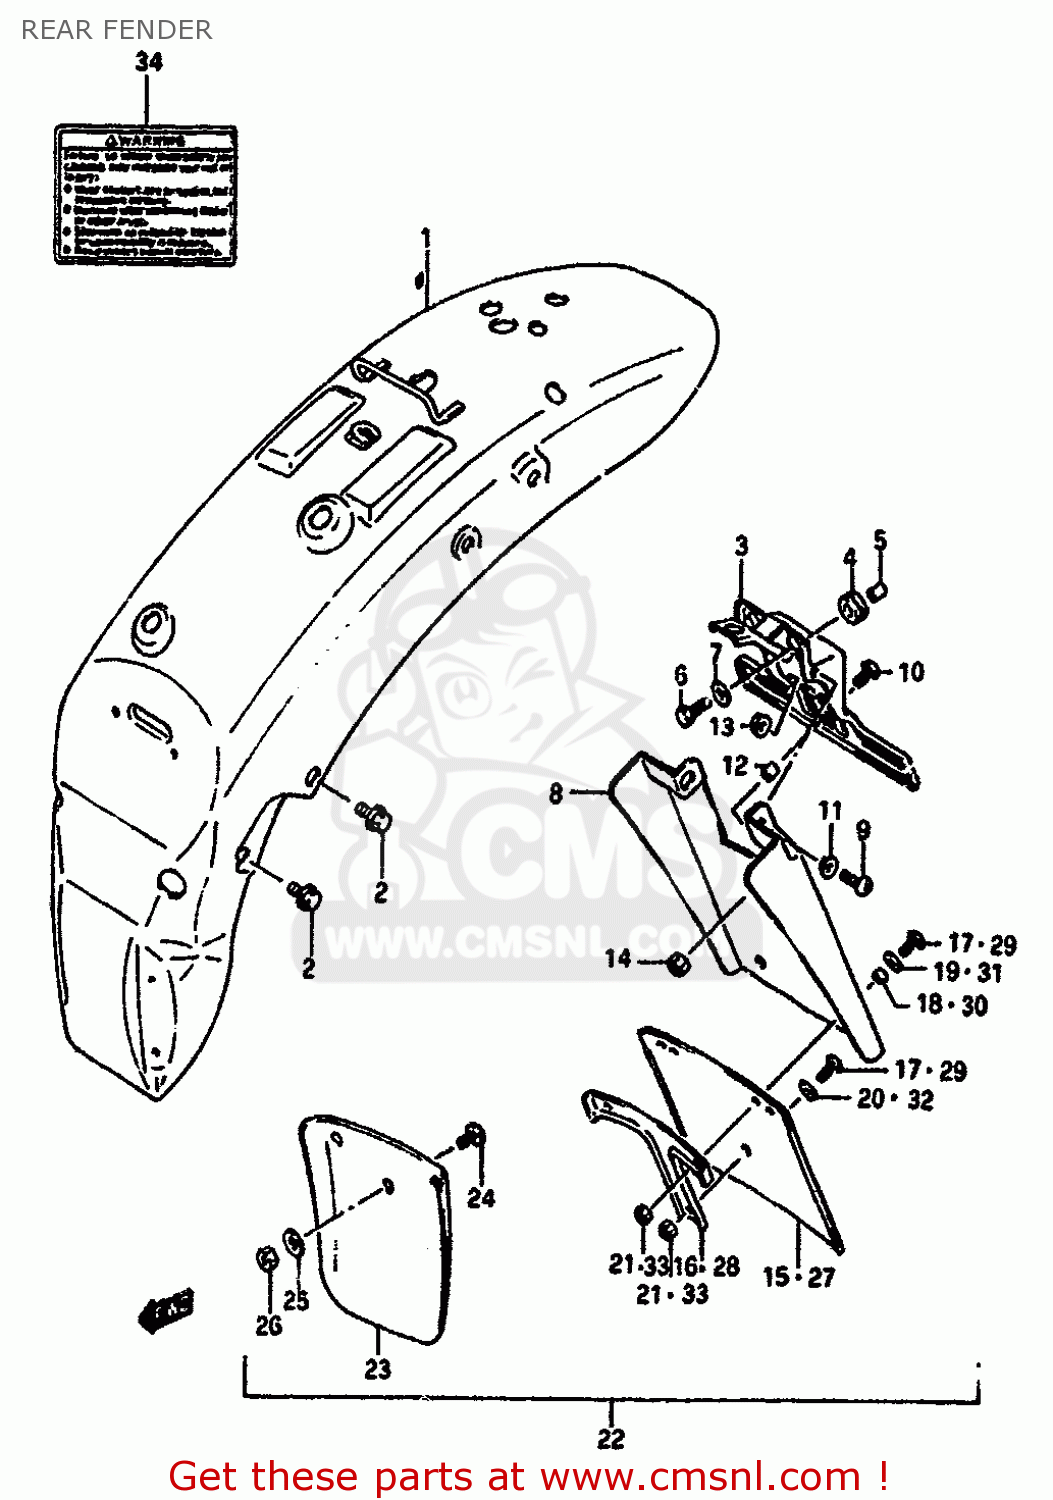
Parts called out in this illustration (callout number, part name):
1	FENDER,REAR
2	BOLT
3	BRACKET,LICENSE LAMP
4	CUSHION
5	SPACER
6	BOLT
7	WASHER
8	EXTENSION,REAR
9	SCREW
10	SCREW
11	WASHER
12	SPACER(6.2X8.3X6.1)
13	NUT 6MM
14	NUT
15	MUD FLAP, REAR FENDER
16	PLATE, MUD FLAP
17	SCREW, FRONT & REAR
18	SPACER (5.5X8X4)
19	WASHER,5MM
20	WASHER
21	NUT 8MM
22	EXTENSION & MUD FLAP SET
23	EXTENSION
24	SCREW
25	WASHER,5MM
26	NUT 5MM
27	MUD FLAP, REAR FENDER
28	PLATE, MUD FLAP
29	SCREW, FRONT & REAR
30	SPACER (5.5X8X4)
31	WASHER,5MM
32	WASHER
33	NUT 8MM
34	LABEL, WARNING SAFETY
